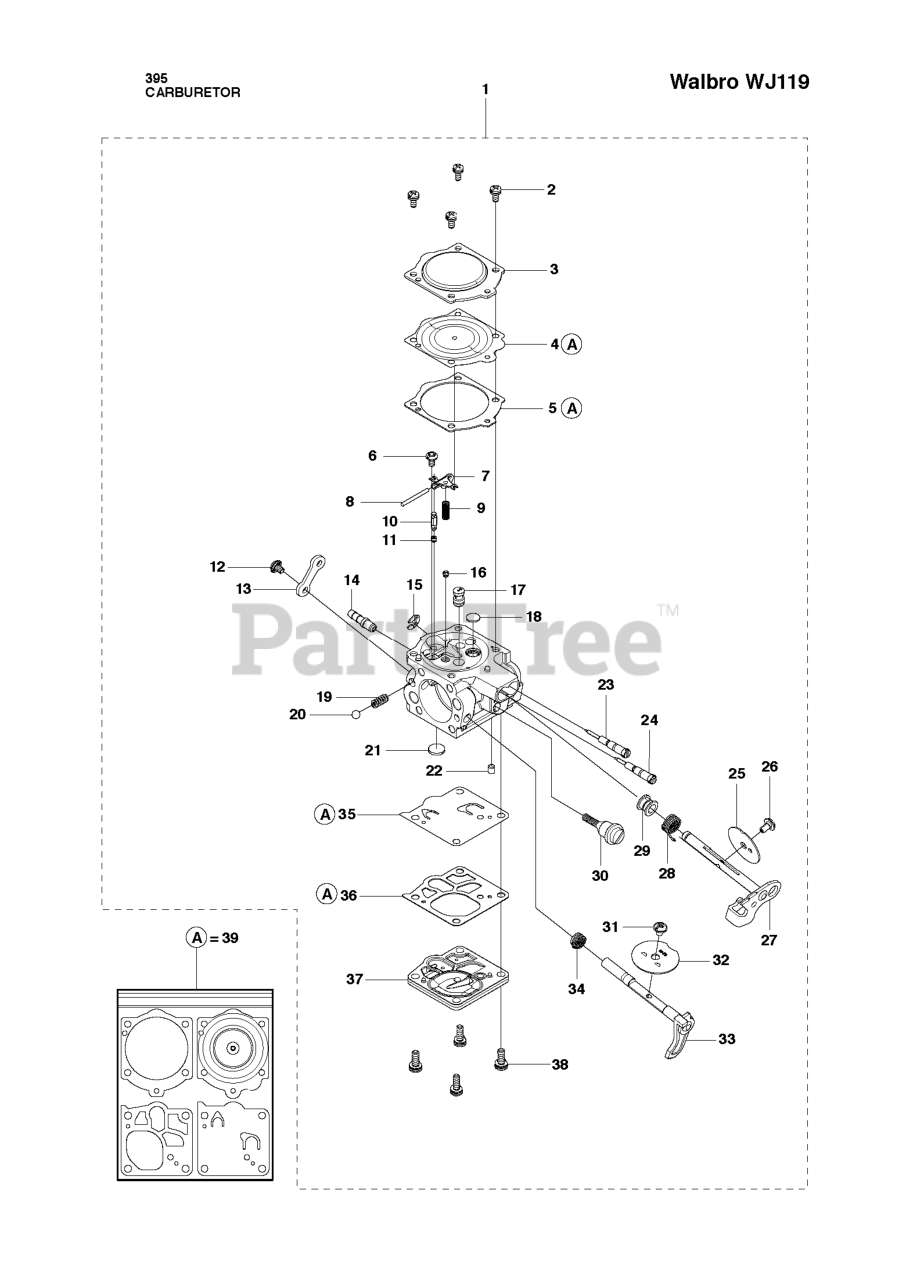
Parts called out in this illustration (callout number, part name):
1	CARBURETOR
2	RP SCREW W/ WASHER
3	DIAPHRAM COVER
4	MAIN DIAPHRAGM
9	SPRING METERING
10	INLET NEEDLE
11	SEAT IN VALVE PLATED
14	FITTING FUEL INLET
15	E CLIP
18	PLUG WELCH
21	FUEL INLET SCREEN
22	PLUG FRICTION
23	NEEDLE IDLE
24	NEEDLE HIGH
25	THROTTLE FLAP
27	SHAFT ASSY THROTTLE
31	SCREW
32	CHOKE FLAP
33	SHAFT ASSY
34	SPRING CHOKE
35	DIAPHRAM PUMP
37	COVER PUMP
38	SCREW W/ WASHER
39	DIAPHRAGM SET
